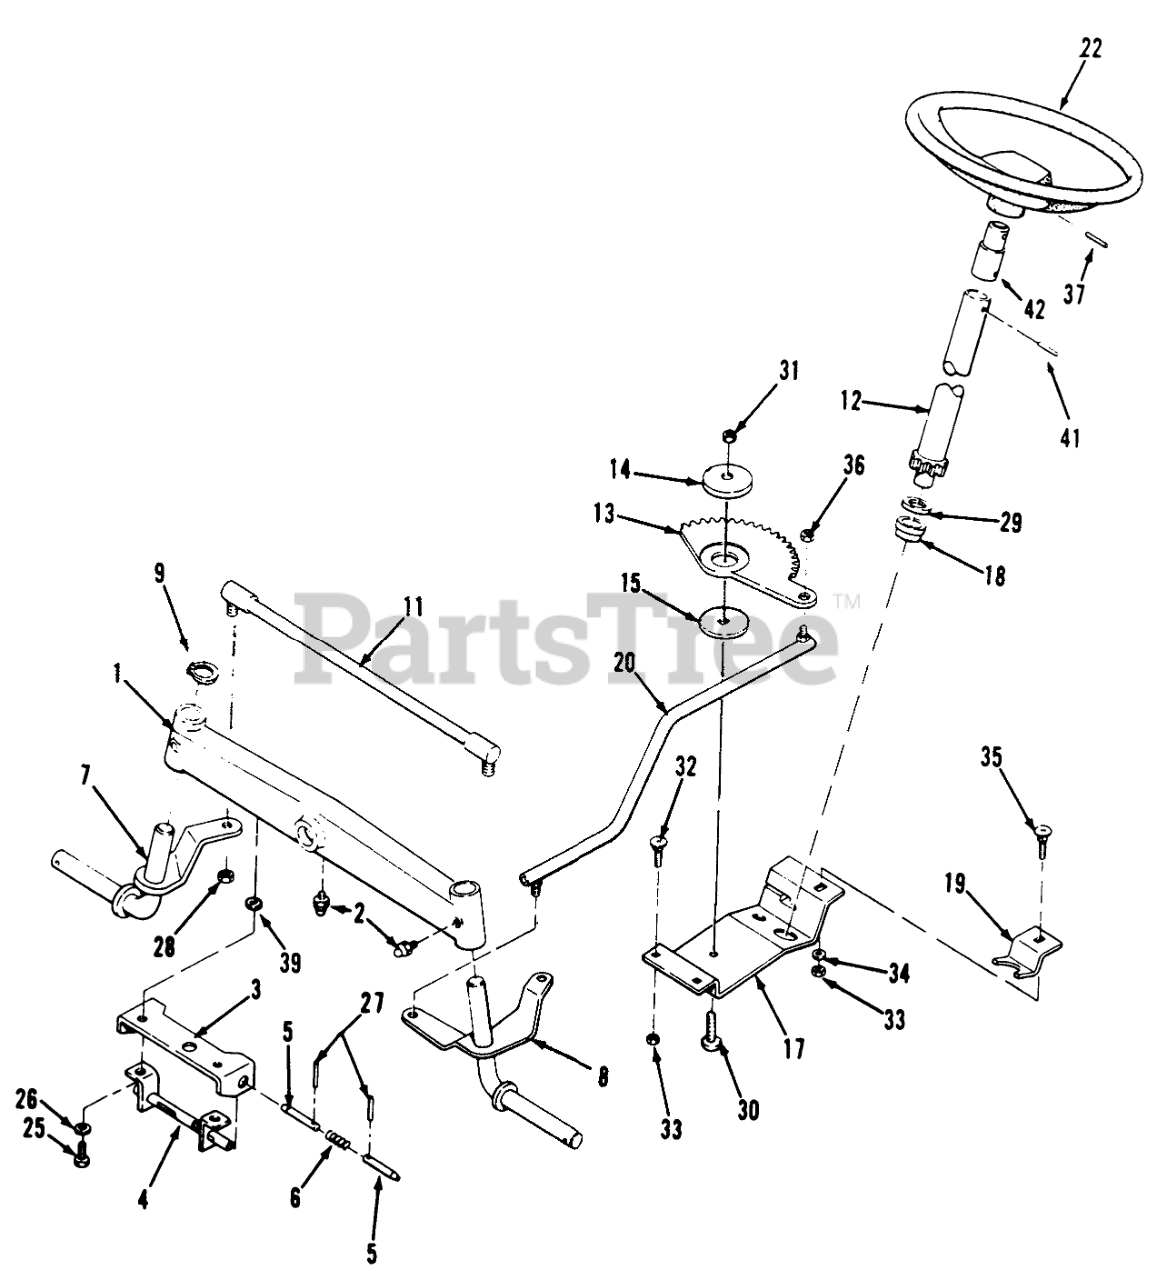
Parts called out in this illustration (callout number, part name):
1	AXLE-FRONT R
2	FITTING-GREASE
3	BRACKET-SUPPORT R
4	TUBE & BRACKET ASM R
6	SPRING
7	ASSY ARM STEERING R
8	ASSY ARM STEERING R
9	RING-RETAINING
11	ASS'Y-TIE ROD R
12	ASSY PINION & SHA B
13	GEAR SECTOR
14	BUSHING
15	WASHER-BEARING
17	BRKT-STEERING GEA R
18	BEARING-WHEEL
19	RETAINER R (NS)
20	ASSY BALL JOINT L R
22	STR'G-WHL 13" TORO
25	SCREW-HH
26	WASHER-LOCK
27	PIN-SPRING
28	Nut-Lock
29	WASHER
30	SCREW-CARR
32	Bolt
33	SCREW-CARR
34	WASHER-PLAIN
35	BOLT-CARR
36	NUT-6
37	SPIROL PIN 5/16X13/8
39	WASHER
41	Pin-Roll
42	SHAFT-COUPLER
